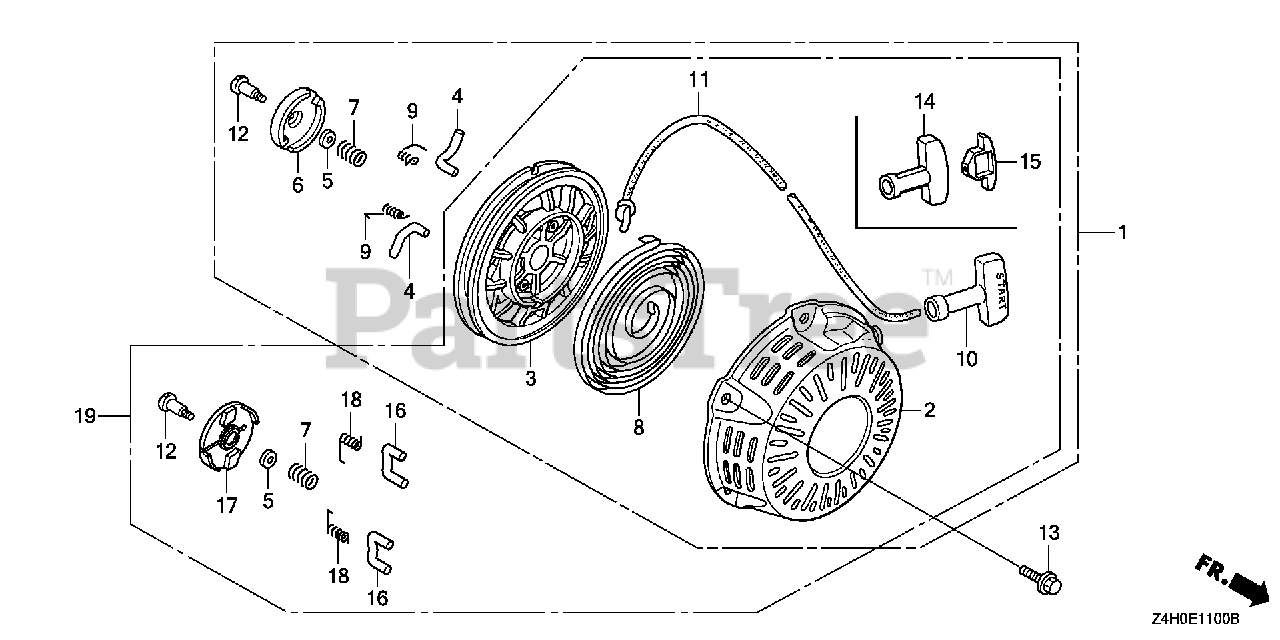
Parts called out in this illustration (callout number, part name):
1	STARTER ASSY., RECOIL *R280* (POWER RED)
2	CASE, RECOIL STARTER *R280* (Honda Code 7346836). (POWER RED)
3	REEL, RECOIL STARTER
3	REEL, RECOIL STARTER (BLACK)
4	RATCHET, STARTER
5	PLATE, FRICTION
6	GUIDE, RATCHET
7	SPRING, FRICTION
8	SPRING, RECOIL STARTER
9	SPRING, RETURN
10	KNOB, RECOIL STARTER
10	GRIP, STARTER
11	ROPE, RECOIL STARTER (#5X55")
12	SCREW, SETTING
13	BOLT, FLANGE (6X10)
